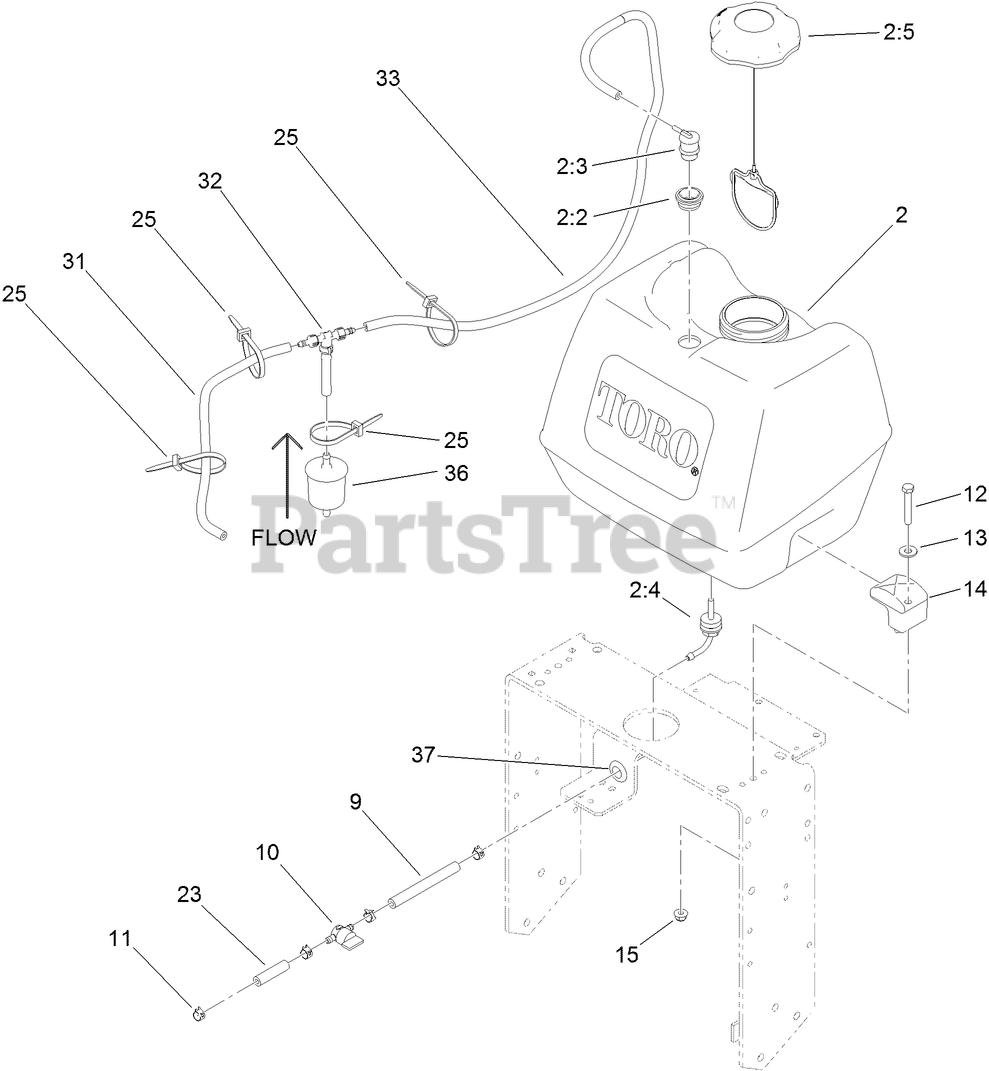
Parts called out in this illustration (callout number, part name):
2	FUEL TANK ASM
2:2	GROMMET
2:3	VALVE-VENT, FUEL
2:4	FITTING-FUEL, BULKHEAD
2:5	CAP-FUEL, RATCHETING
9	HOSE-FUEL
10	VALVE-FUEL
11	CLAMP-HOSE
12	SCREW-HH
13	WASHER-FLAT
15	NUT-HF, NI
23	HOSE-FUEL
25	TIE-CABLE
31	HOSE-FUEL
32	TEE AND CHECK
33	HOSE-EMISSIONS
36	FILTER-FUEL
37	GROMMET
